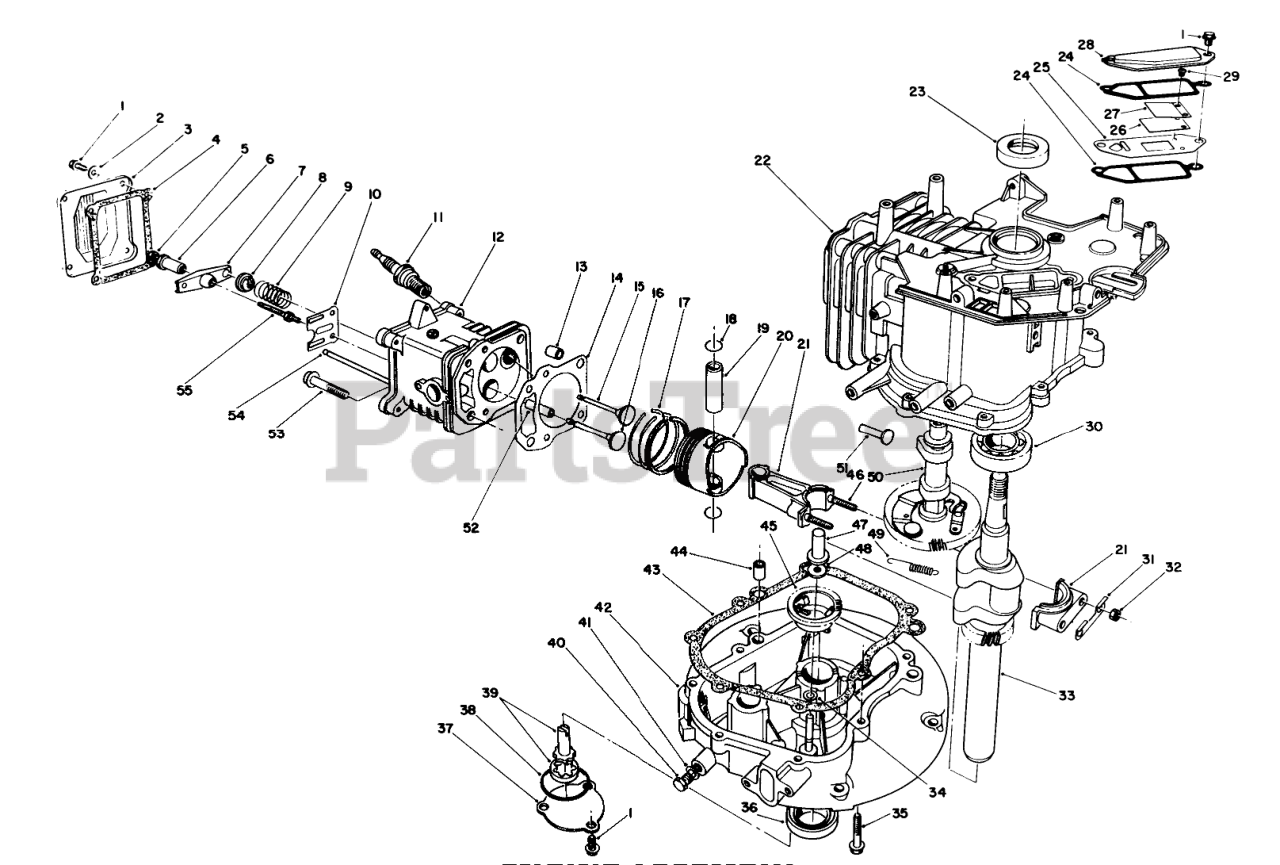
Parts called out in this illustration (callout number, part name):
2	WASHER
3	COVER
4	GASKET
6	PIVOT
8	RETAINER
9	SPRING
10	GUIDE
11	SPARK PLUG
12	Head-Cylinder (Incl. Ref. #52)
14	GASKET
15	VALVE-INTAKE
16	VALVE-EXHAUST
17	RING SET
18	CIRCLIP
20	PISTON
21	Connection Rod Assembly (Incl. Ref. #31, 32, & 46)
22	Block-Engine (Incl. Ref. #23, & 30)
24	GASKET
25	Plate-Breather
26	Valve-Reed
27	Retainer-Reed Valve
28	COVER
29	Screw-Reed Valve
30	BEARING
31	Plate-Lock
33	CRANKSHAFT
34	WASHER
36	Oil Seal
37	COVER
38	O-RING
39	OIL PUMP
40	OIL DRAIN PLUG
41	GASKET
42	Crankcase
43	GASKET
45	GOVERNOR FLYWEIGHT ASM
47	PLUNGER
48	WASHER
49	SPRING
50	Camshaft Assy. (Incl. Ref. #49)
51	TAPPET
52	GUIDE
